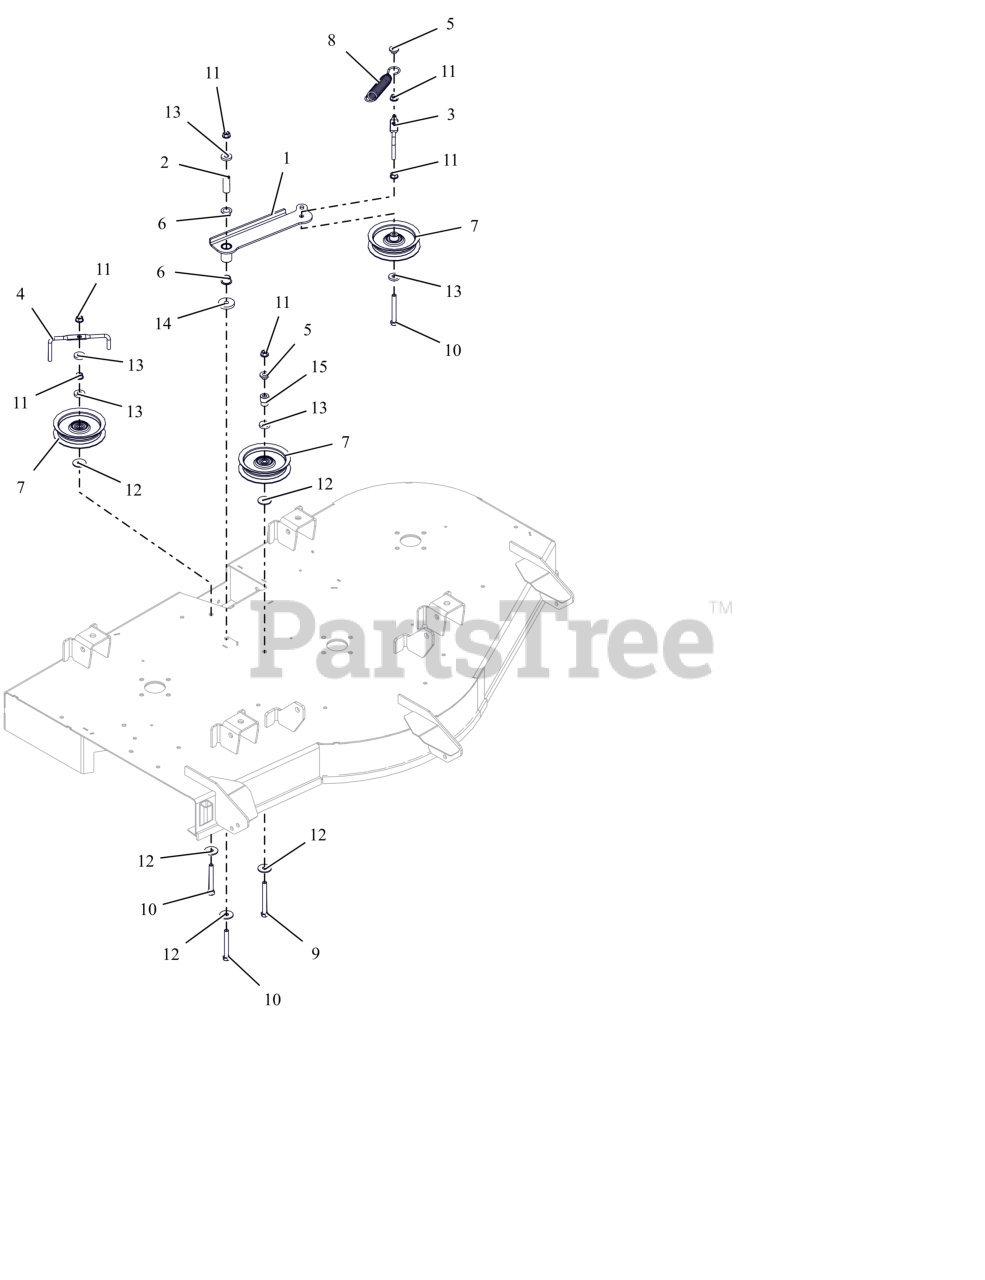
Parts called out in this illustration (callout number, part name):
1	WLDMT, IDLER ARM-52"
2	SPACER, .375IDX.625ODX1.66 PM
3	WIREFORM, BELT FINGER
4	BELT FINGER
5	BSHG-FLG .385X.500X.875X.406
6	BSHG-FLG, .625X.750X.500X1.00
7	IDLER, FLAT - 4.06" X .75"
8	SG-TENS .135X.98X6.0 WLD 62
9	BLT, HEX .38-16X3.50 G5 ZCC
10	BLT, HEX .38-16X3.00F G5 ZCC
11	NUT-LK-CTR-FLG .375-16 GF ZCC
12	WSHR FL STL .406X1.25X.10ZC120
13	WSHR, FLT .406X1.00X.188 ZCC
14	WSHR, FLT .406X1.50X.245 ZCC
15	BUSHING, IDLER (P/M)
